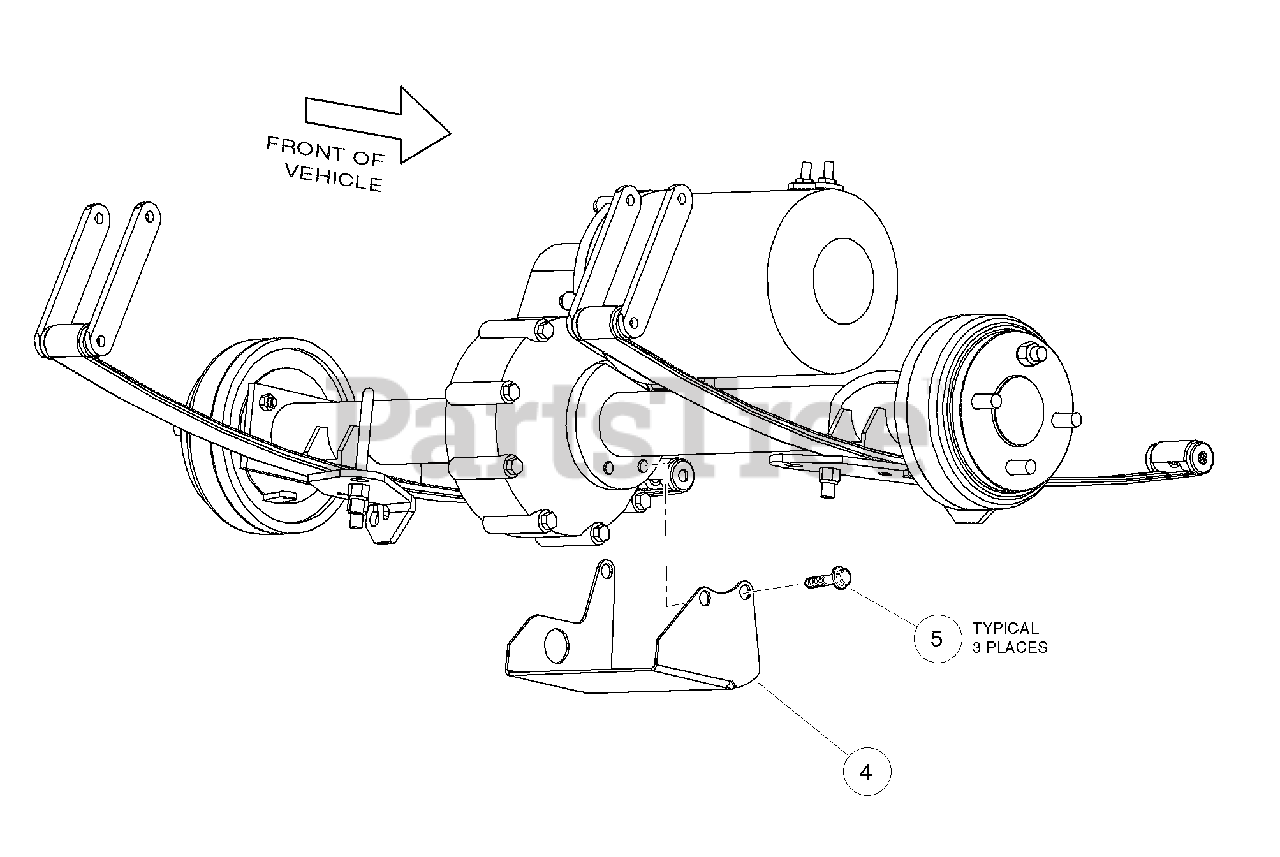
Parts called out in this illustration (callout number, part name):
1	Differential Guard Kit
2	Kit - Support Brace
3	Screw, M10-1.50 X 60mm Hex Cap
4	Guard, Elect.axle Differential
5	Screw, Flg Hd M10 X 1.5 X 30
